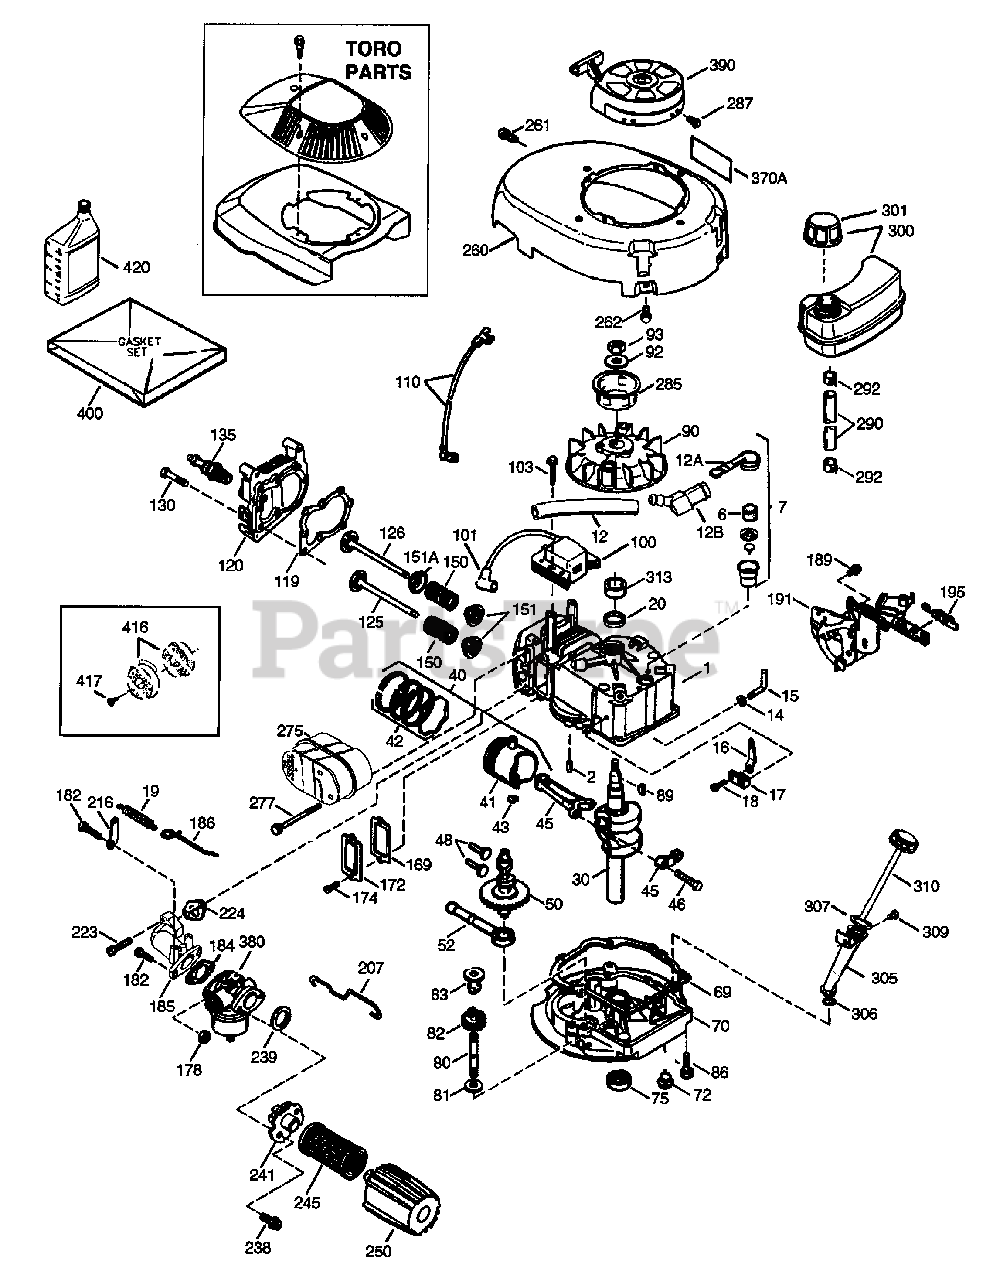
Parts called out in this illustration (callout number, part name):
1	Cylinder (Incl. 2 & 20)
2	Dowel Pin
6	Breather Element
7	Breather Body ASM (Incl. 6 & 12A)
12	Breather Tube
12A	Breather Cover & Tube (Incl. 12B)
12B	Breather Tube Elbow
15	Governor Rod (Incl. 14)
16	Governor Lever
17	Governor Lever Clamp
19	Extension Spring
20	Oil Seal
30	Crankshaft
40	Piston, Pin & Ring Set (Std.)
40	Piston, Pin & Ring Set (.010" OS)
41	Piston & Pin ASM (Std.)(Incl. 43)
41	Piston & Pin ASM (.010" OS)(Incl. 43)
42	Ring Set (Std.)
42	Ring Set (.010" OS)
43	Piston Pin Retaining Ring
45	Connecting Rod ASM (Incl. 46)
46	Connecting Rod Bolt
48	Valve Lifter
50	Camshaft (MCR)
52	Oil Pump ASM
69	Mounting Flange Gasket
70	Mounting Flange (Incl. 72 thru 83)
72	Oil Drain Plug
75	Oil Seal
80	Governor Shaft
82	Governor Gear ASM (Incl. 81)
83	Governor Spool
89	Flywheel Key
90	Flywheel
92	Belleville Washer
93	Flywheel Nut
100	Solid State Ignition
101	Spark Plug Cover
103	Screw, Torx T-15
110	Ground Wire
119	Cylinder Head Gasket
120	Cylinder Head
125	Exhaust Valve (Std.)(Incl. 151)
125	Exhaust Valve (1/32" OS)(Incl. 151)
126	Intake Valve (Std.)(Incl. 151)
126	Intake Valve (1/32" OS)(Incl. 151)
135	Resistor Spark Plug (RJ19LM)
150	Valve Spring
151	Valve Spring Cap
151A	Intake Valve Seal
169	Valve Cover Gasket
172	Valve Cover
178	Nut & Lock Washer
182	Screw
184	Carburetor To Intake Pipe Gasket
185	Intake Pipe
186	Governor Link
191	S.E. Brake Bracket (Incl. 195)
195	Terminal
207	Throttle Link
216	R.P.M. Adjusting Lever
224	Intake Pipe Gasket
239	Air Cleaner Gasket
241	Air Cleaner Collar
245	Air Cleaner Filter
250	Air Cleaner Cover
260	Blower Housing
275	Muffler
285	Starter Cup
290	Fuel Line
292	Fuel Line Clamp
300	Fuel Tank (Incl. 292 & 301)
301	Fuel Cap
305	Oil Fill Tube
306	"O"-Ring
307	"O"-Ring
310	Dipstick
370A	Lubrication Decal
380	Carburetor (Incl. 184)
390	Rewind Starter (NOTE: This engine could have been built with 590739 starter. Refer to the design of the rope pulley strength ribs for part identification. Individual starter parts do not interchange. Refer to service bulletin 116.
400	Gasket Set (Incl. Items Marked PK in Notes) Incl. part #'s 26756 (1), 28833 (1), 34338 (1), 36783 (1), 36786 (1), 36787 (1), 36832 (1), 36996 (1), 37130 (1).
416	Spark Arrestor Kit (Incl. 417) (Optional)
417	Screw (Optional)
420	SAE 30 4-Cycle Engine Oil (Quart)
